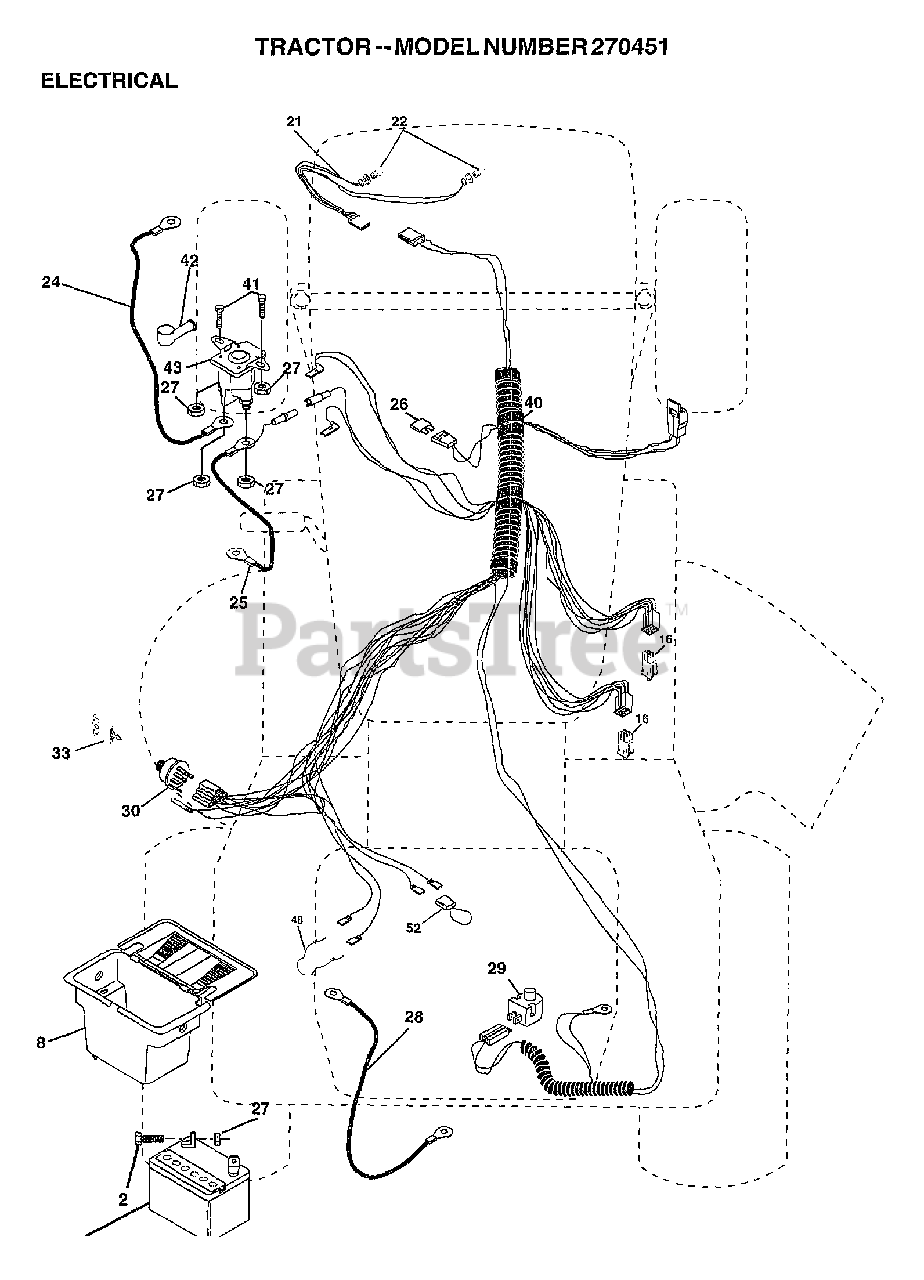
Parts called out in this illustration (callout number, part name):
2	BOLT LT
8	"CASE,BATTERY.MECH"
16	SWITCH INTERLOCK
21	HARNESS.ASM.LIGHT W/4152J
22	HEADLAMP BULB
24	"CABLE T, BATTERY"
25	CABLE.BTRY.6GA.RD
26	FUSE.15 AMP
27	NUT
28	CABLE T
29	SWITCH SEAT
30	SWITCH.IGN.
33	KEY MLD GEN DELTA
40	HARNESS IGN
41	BOLT HXHD FIN
48	ADAPTER AMMETER
52	PROTECTION LOOP
